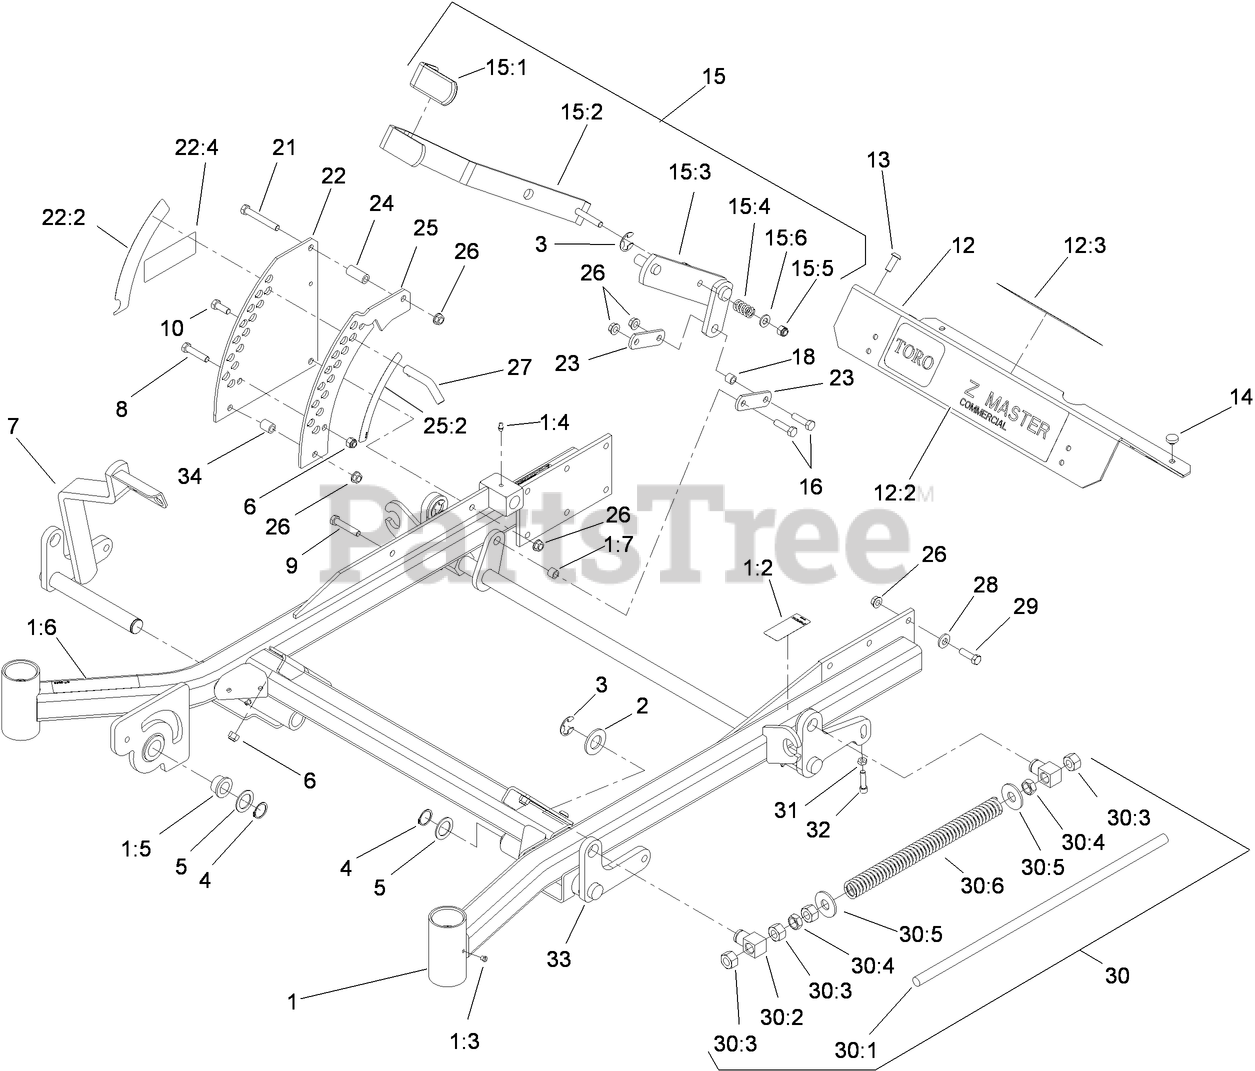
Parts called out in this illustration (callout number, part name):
1	Frame ASM
1:2	Decal-Brake, Parking
1:4	FITTING-GREASE
1:5	BUSHING
1:6	DECAL-WARNING
1:7	Bushing
2	WASHER-FLAT
3	RING-RETAINING, EXT
4	RING-RETAINING
5	WASHER-SPACER
6	NUT-LOCK, NI
7	LIFT-DECK, RH FRONT
8	SCREW-HH
9	SCREW-HH
10	SCREW-HH
12	FOOTREST
12:3	DECAL-WARNING
13	SCREW-HSBH
14	BUMPER
15	DECK LIFT HANDLE ASM
15:1	GRIP-LEVER, LIFT
15:2	LEVER-LIFT
15:3	ARM-LIFT, DECK
15:4	SPRING-COMPRESSION
15:5	NUT-LOCK, NI
15:6	WASHER-FLAT
16	SCREW-HH
18	Bushing
21	SCREW-HH
22	PLATE-HOC, OUTER
22:2	Decal-Height, Deck
22:4	DECAL-ARRESTER, SPARK
23	ARM-LIFT, DECK
24	BUSHING-LEVER, LIFT
25	PLATE-HOC, INNER
25:2	Decal-Height, Deck
26	NUT-HHF, WHIZ
27	PIN-HOC
28	WASHER-BELLEVILLE
29	SCREW-HH
30	FRONT FRAME SPRING ASM
30:1	ROD-LIFT, DECK
30:2	SWIVEL-DECK MOUNT, REAR
30:3	NUT-HEX
30:4	NUT-JAM
30:5	WASHER-FLAT
30:6	SPRING-SUPPORT, DECK
31	NUT-JAM
32	SCREW-HSH
33	LIFT-DECK, LH
34	BUSHING-LEVER, LIFT
